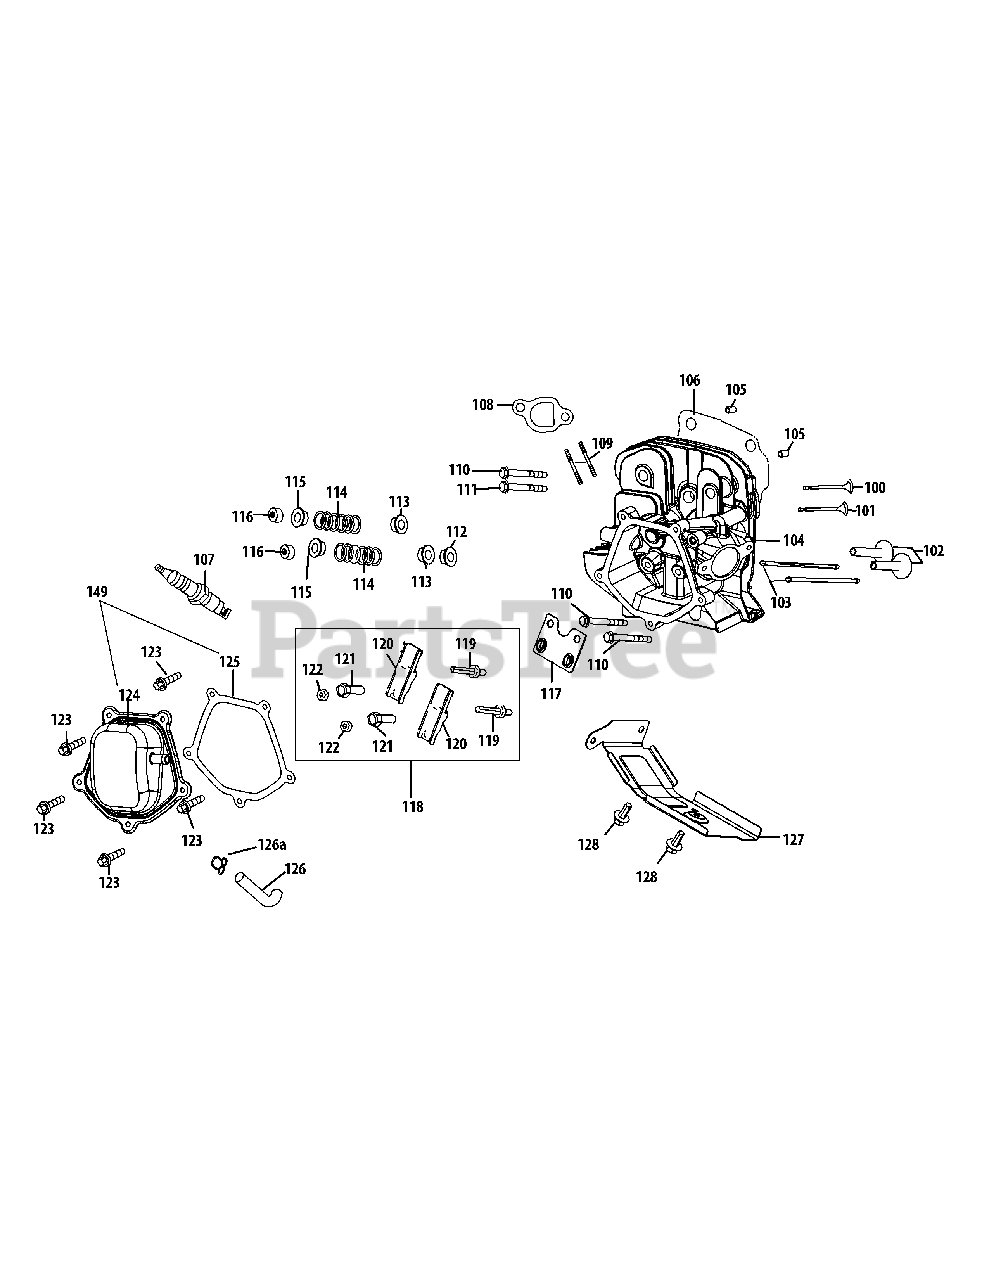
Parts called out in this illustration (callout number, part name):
102	Tappet
104	Cylinder Head Kit
105	Dowel Pin 12×20
106	Gasket Cylinder Head
107	Spark Plug
108	Exhaust Pipe Gasket
109	Stud M8×48.5
109	Muffler Stud Assembly
110	Bolt M10×1.25×87
111	Bolt M10×1.25×65
112	Intake Valve Seal
113	Valve Spring Retainer
114	Valve Spring
115	Retainer Ex. Valve Spring
116	Adjuster Ex. Valve
117	Push Rod Guide
118	Rocker Arm Assembly
119	Bolt Pivot
120	Rocker Arm
121	Adjusting Nut ,Valve
122	Nut Pivot Locking
123	Valve Cover Bolt
124	Valve Cover
125	Valve Cover Gasket
126	Breather Hose
127	Air Shield
128	Bolt M6×12
149	Valve Cover Kit
